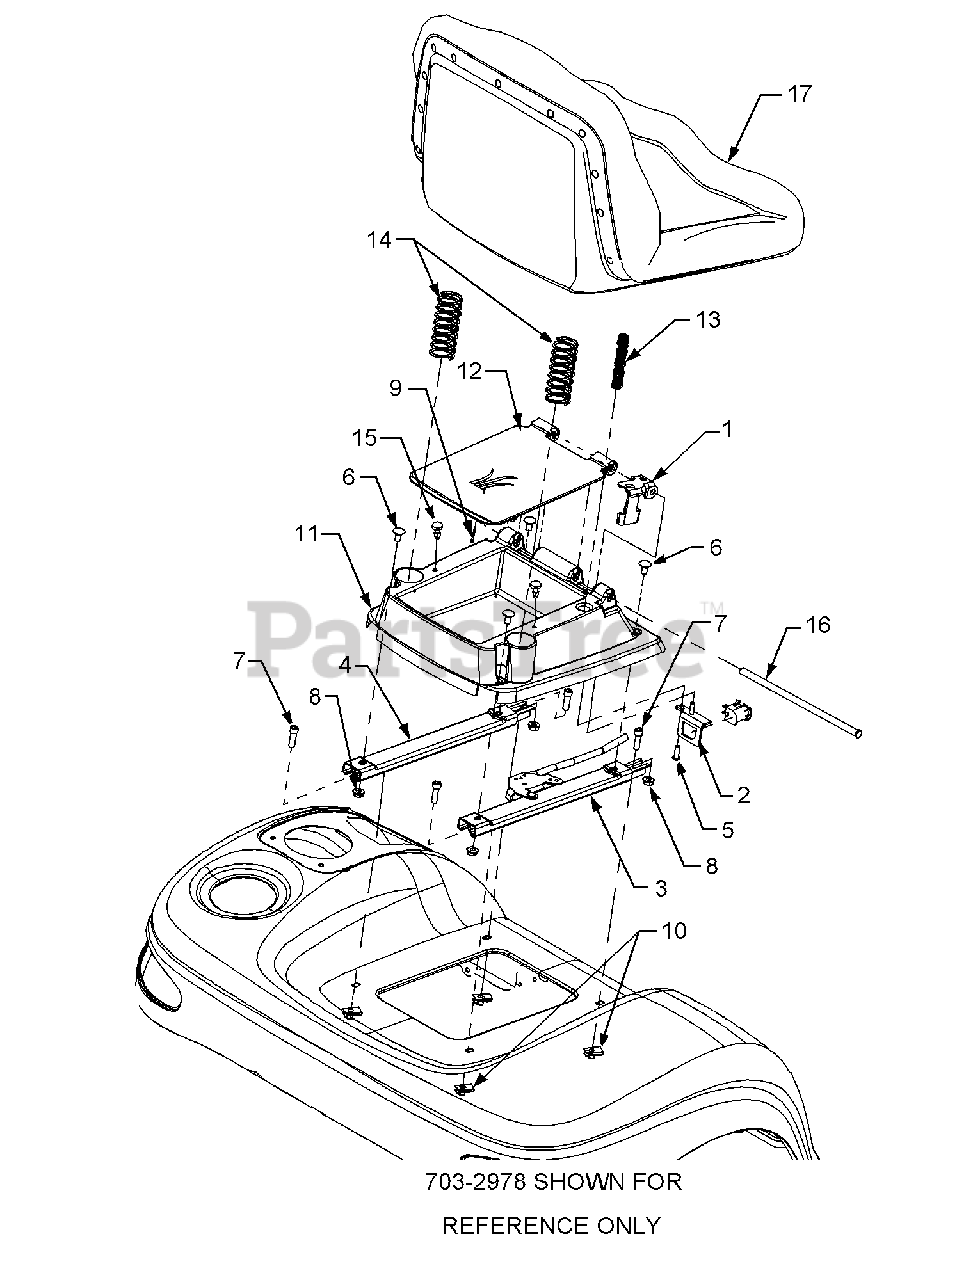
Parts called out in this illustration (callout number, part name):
4	Track, Seat, w/o Latch
5	Screw, Pan Torx Hd., #12-14 x .5
6	Carriage Bolt, 5/16-18 x .62
7	Screw, Pan Torx Hd. 5/16-18 x 1.0
8	Nut, Hex Flange Lock, 5/16-18
9	Pin, Cotter, 3/32 x .75
10	Speed Nut, U-Type, 5/16-18
11	Base, Seat
12	Lid, Tlbx
13	Spring, Compression
14	Spring, Compression
15	Bumper
16	Rod, Seat Pivot
17	Seat, High Back
